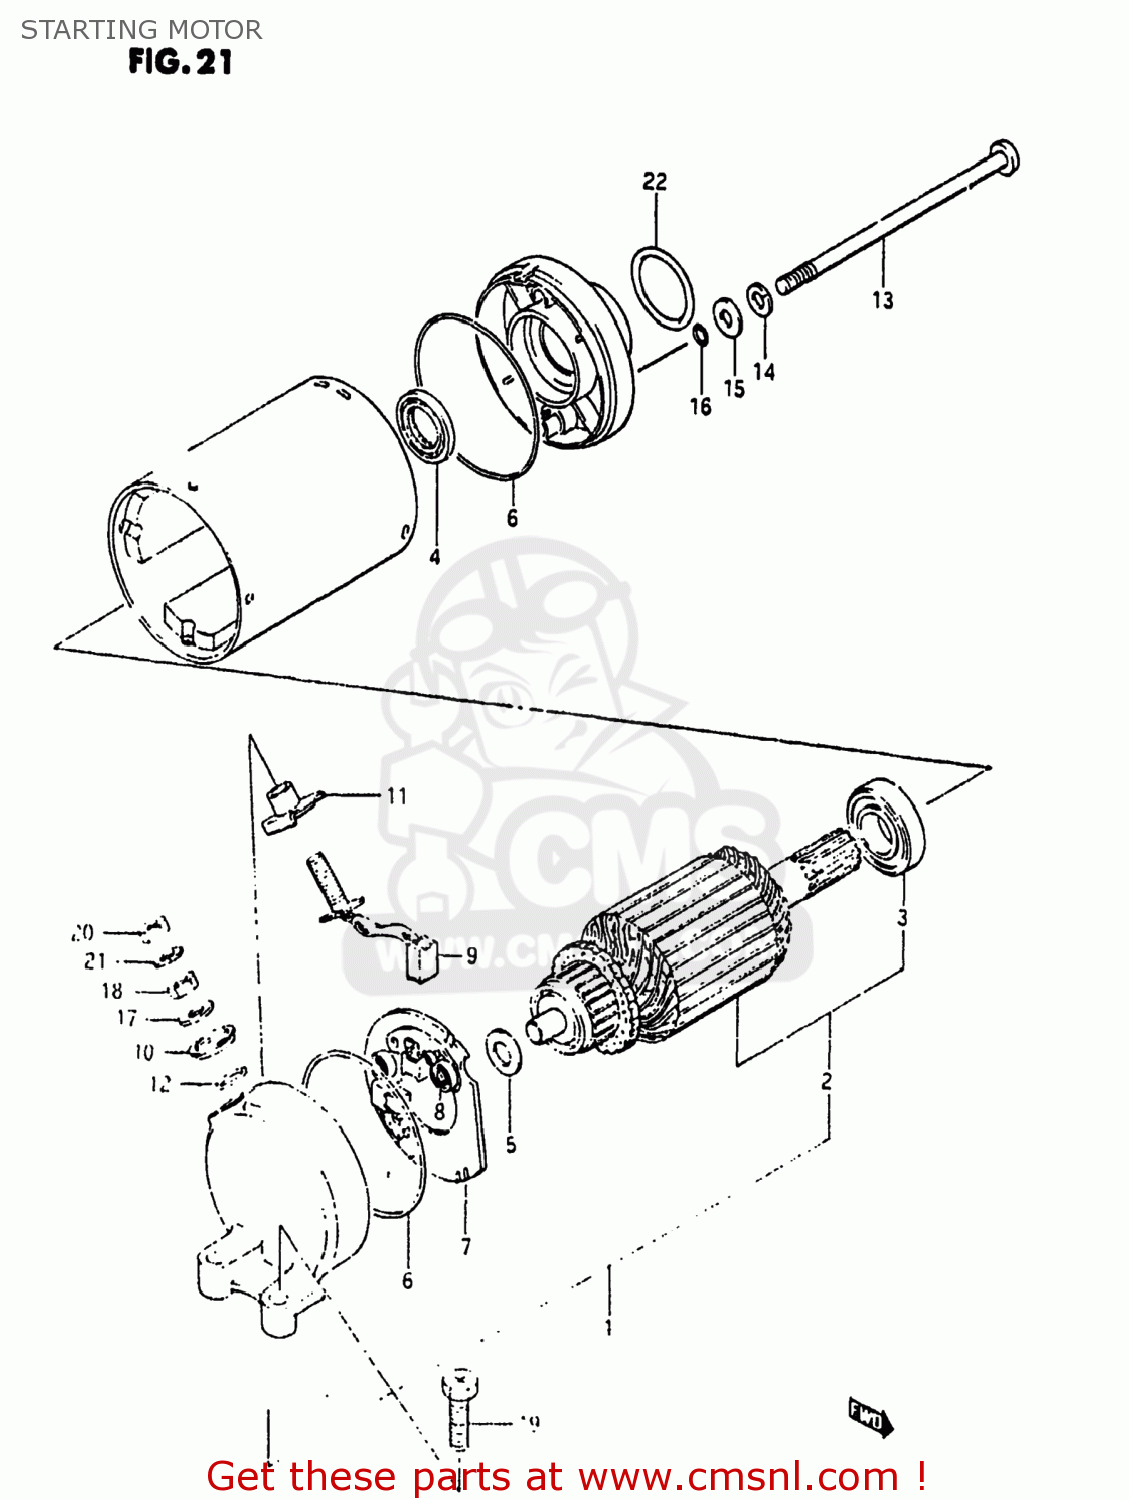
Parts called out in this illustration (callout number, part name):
1	MOTOR ASSEMBLY,STARTING
2	ARMATURE
3	BEARING
4	SEAL,OIL
5	SHIM,ARMATURE
6	O RING
7	HOLDER,BRUSH
8	SPRING
9	BRUSH SUB ASSY,STARTING MOTOR
10	BUSHING
11	BUSH,B
12	O RING
13	BOLT
14	LOCK WASHER
15	WASHER
16	O RING
17	WASHER
18	NUT 6MM
19	SCREW (6X25)
20	NUT
21	WASHER,LOCK
22	O RING(D:3,ID:24.5)
